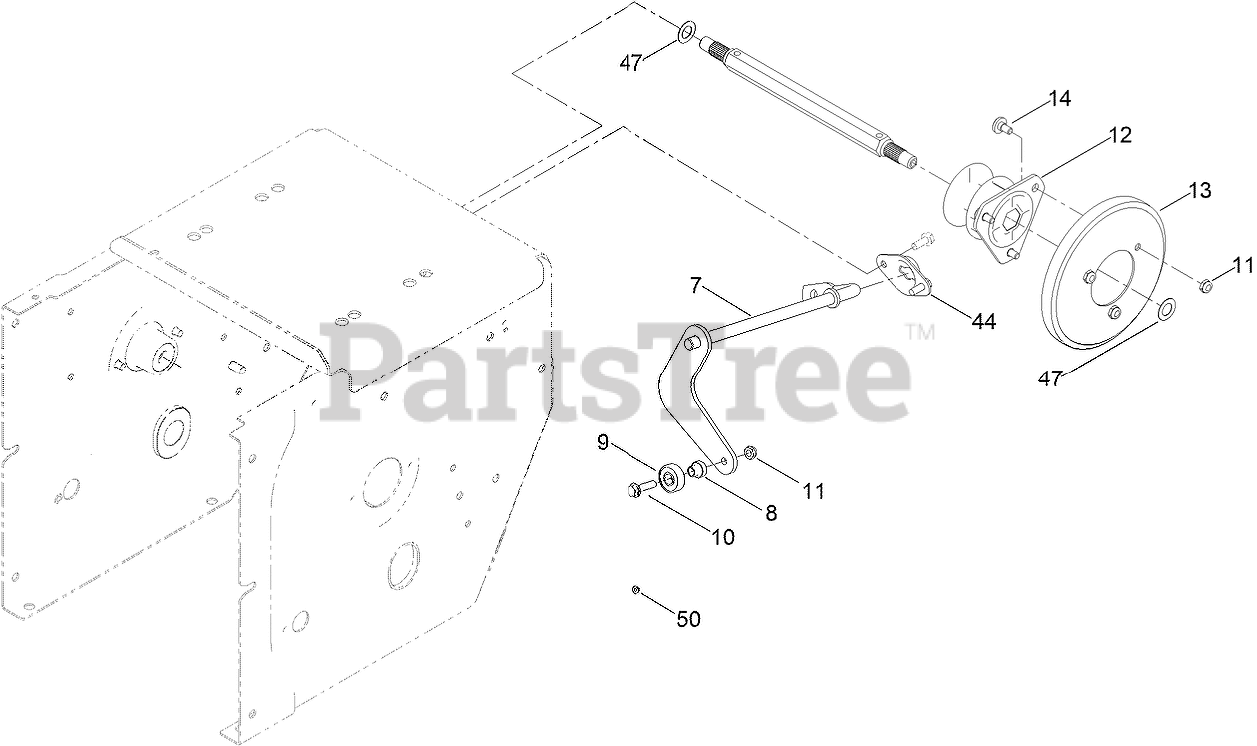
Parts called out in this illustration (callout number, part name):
7	ROD-SHIFT
8	SPACER-PLATE, SHIFT
9	BEARING-BALL
10	SCREW-HWHTF
11	NUT-HEX
12	TRUNNION
13	WHEEL-FRICTION
14	SCREW-SHOULDER
44	RETAINER-ROD, SHIFT
47	WASHER-PLAIN
50	NUT-FLANGE, NI
